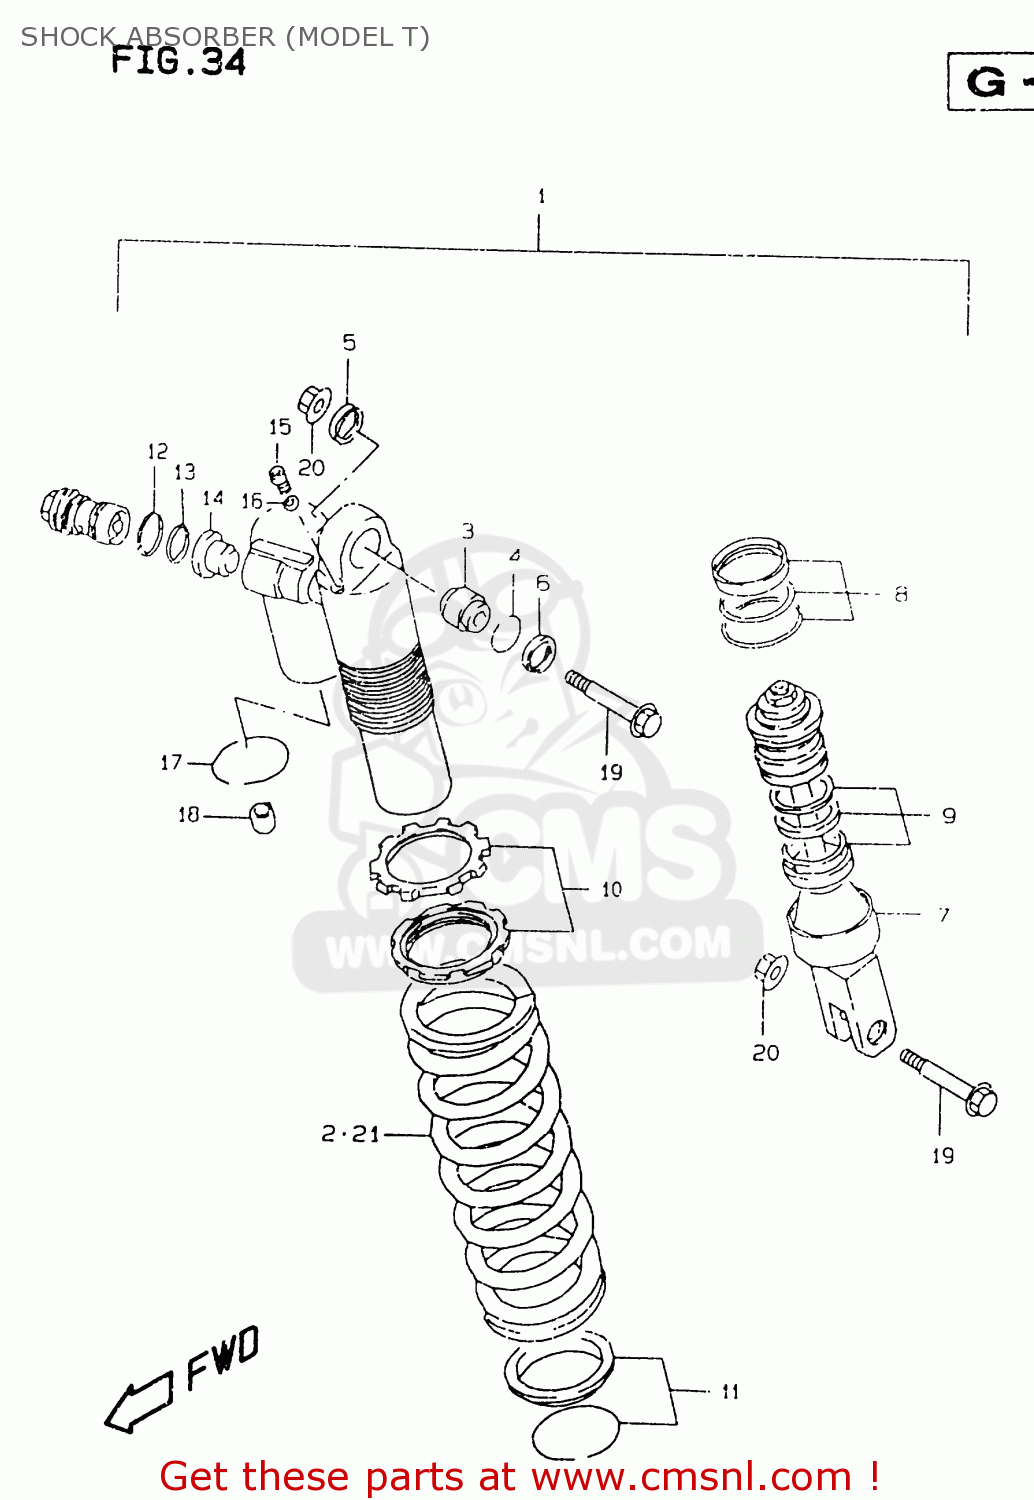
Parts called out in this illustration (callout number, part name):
1	ABSORBER ASSEMBLY,REAR SHOCK
2	SPRING,RR(K=4.8)
3	BEARING,RR SHOCK ABSORBER
4	RING,STOPPER
5	SEAL,DUST UPR,R
6	SEAL,DUST UPR,L
7	ROD,PISTON
8	O RINR SET
9	RING STOPPER SET,ABSORBER
10	ADJUSTER SET,SHOCK ABSORBER
11	SPRING SEAT SET,SHOCK ABSORBER
12	O RING
13	O RING,CTR BOLT UPR
14	COLLAR,ORIFICE
15	BOLT
16	GASKET,DRAIN,PLUG (NAS)
17	RING,STOPPER
18	CAP
19	BOLT(10X47.5)
20	NUT
21	SPRING,RR(K=4.6)
